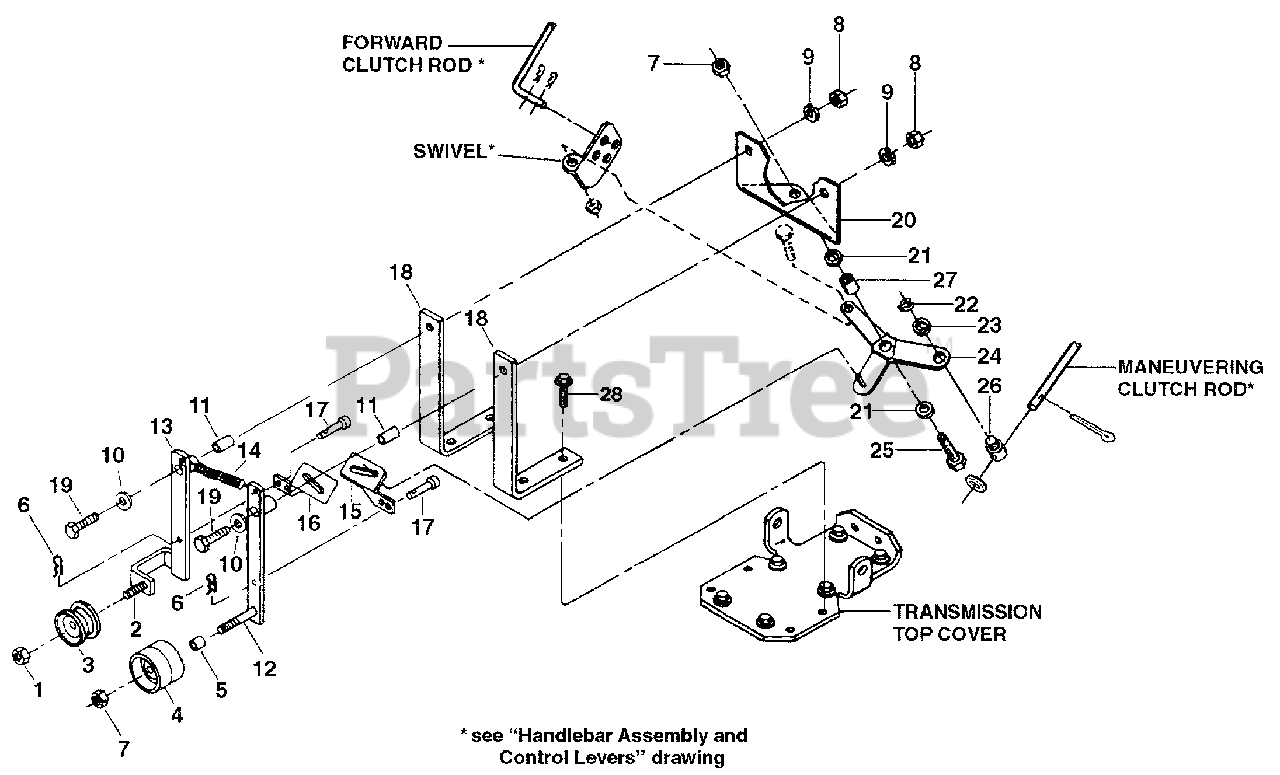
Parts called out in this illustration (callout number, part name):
1	Locknut-hex, 3/8-16
2	Screw-hex hd, 3/8-16 x 1-1/4
3	Pulley-idler, reverse tiller direction
4	Pulley-idler, forward tiller direction
5	Spacer
6	Hairpin Cotter
7	Locknut-hex, 3/8-16
8	Nut-hex, 5/16-18
9	Lockwasher-5/16
10	Washer-plain, 5/16
11	Pivot Bushing
12	Idler Arm-left, forward tiller direction
13	Idler Arm-right, reverse tiller direction
14	Spring
15	Forward Link
16	Reverse Link
17	Pin
18	Mounting Bar
19	Screw-hex hd., 5/16-18 x 2-1/4
20	Shifting Base
21	Spacer-Bushing
22	Klip Ring
23	Washer-pivot
25	Screw-hex hd., 3/8-16 x 1-1/4
26	Pivot-for Reverse Clutch lever
27	Bushing-bellcrank
28	Screw-flanged hex hd., 5/16-18 x 1
